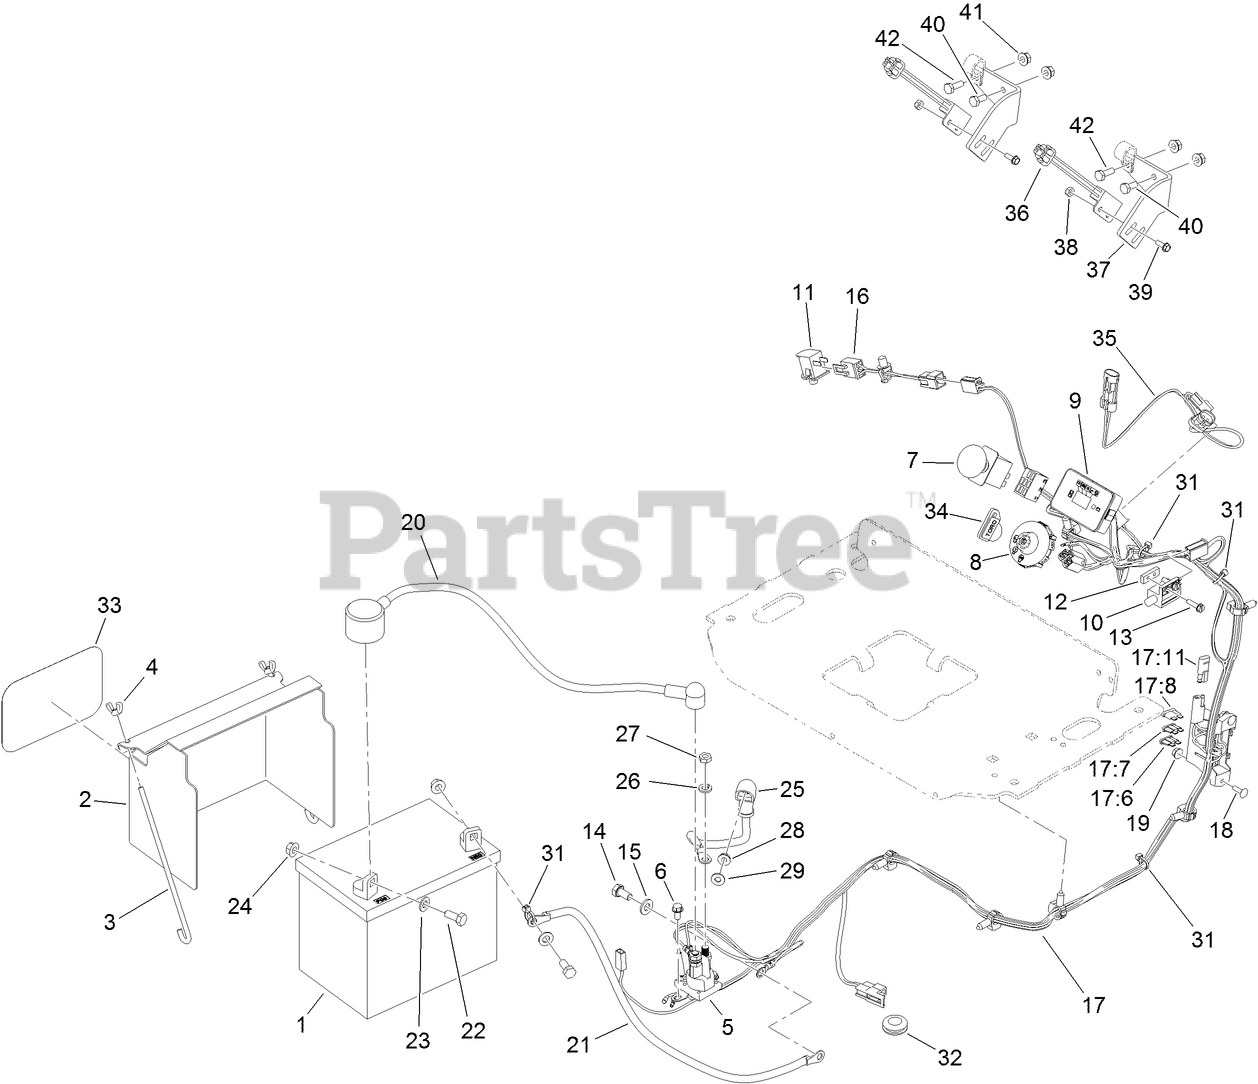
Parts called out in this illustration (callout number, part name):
1	BATTERY-DRY
2	COVER-BATTERY
3	BOLT-HOLDDOWN
4	WINGNUT
5	SOLENOID
6	SCREW-HWH
7	SWITCH-PTO, ON-ON-(ON)
8	SWITCH-IGNITION
9	MODULE-HOUR METER
10	SWITCH-CLOSED, NORMALLY
11	SWITCH-BAIL
12	PLATE-TAPPED
13	SCREW-HWH
14	SCREW-HH
15	WASHER-PLAIN
16	HARNESS-WIRE, JUMPER (OPC)
17	HARNESS-WIRING
17:6	FUSE-BLADE, 30 AMP
17:7	FUSE-BLADE, 25 AMP
17:8	FUSE-BLADE, 10 AMP
17:11	CAP-PLUG
18	BOLT-CARR
19	NUT-HF
20	CABLE-BATTERY, POSITIVE
21	CABLE-BATTERY, BLACK
22	SCREW-HH
23	WASHER-PLAIN
24	NUT-HHF, SMOOTH
25	CABLE-BATTERY, RED
26	WASHER-LOCK
27	NUT-JAM
28	NUT-HF
29	WASHER-FLAT
31	TIE-CABLE
32	GROMMET
33	DECAL
34	KEY-IGNITION
35	HARNESS-WIRE, NEUTRAL SWITCH
36	SWITCH-PROXIMITY
37	BRACKET-MOUNT, SWITCH
38	NUT-LOCK, NI
40	SCREW-HH
41	NUT-HHF
42	SCREW-HH
